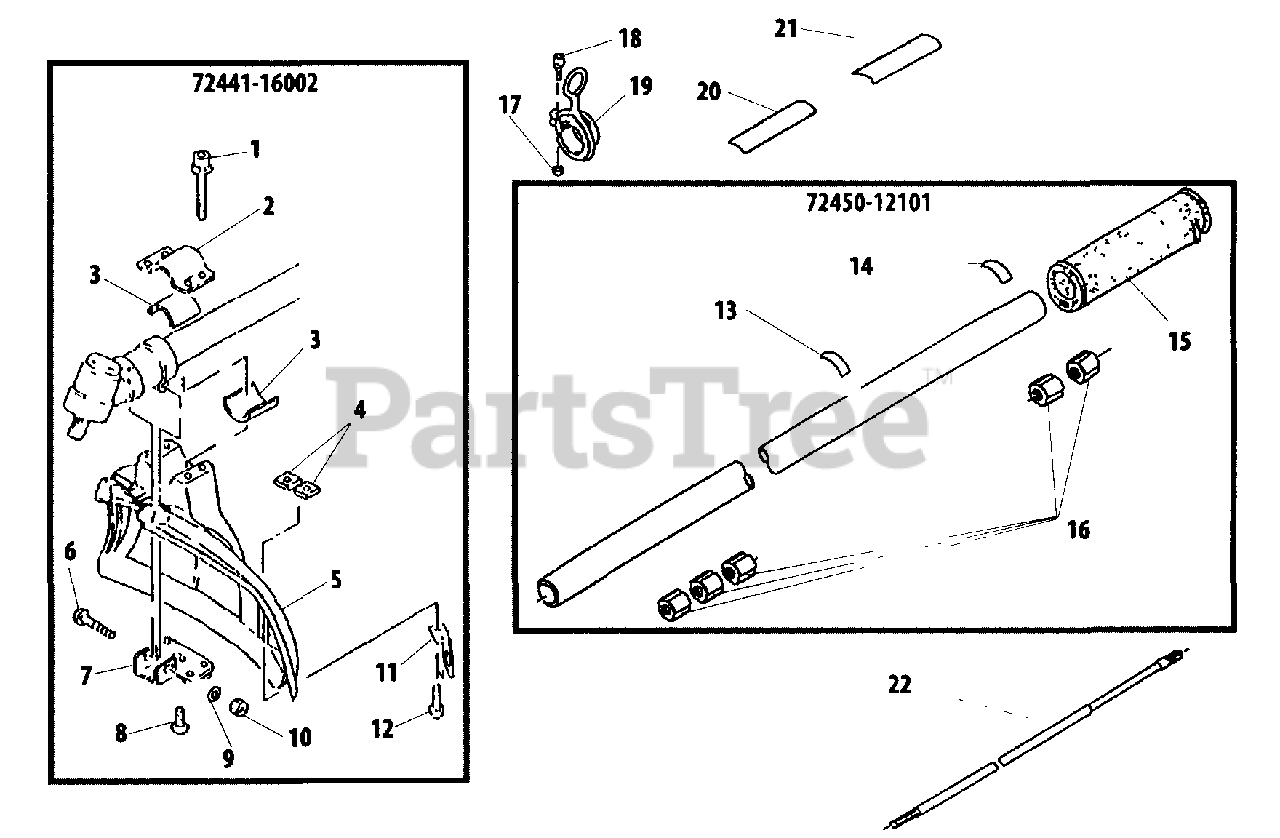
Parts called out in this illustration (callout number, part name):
1	SCREW - 5X50
2	CLAMP - UPPER
3	SPACER
4	NUT - 5
5	SHIELD, DEBRIS
6	SCREW - 6X40
7	BRACKET
8	SCREW
9	WASHER - 6
10	NUT - 6
11	KNIFE, TRIMMER LINE
12	SCREW - 5X16
13	LABEL - ALIGNMENT
14	LABEL - HANDLE LOCATION
15	GRIP
16	BUSHING
18	SCREW - 5X12
19	HANGER
20	LABEL - CAUTION
21	LABEL - MODEL
22	PIPE, MAIN
72441-16002	DEBRIS SHIELD KIT
72450-12101	MAIN PIPE ASSY
